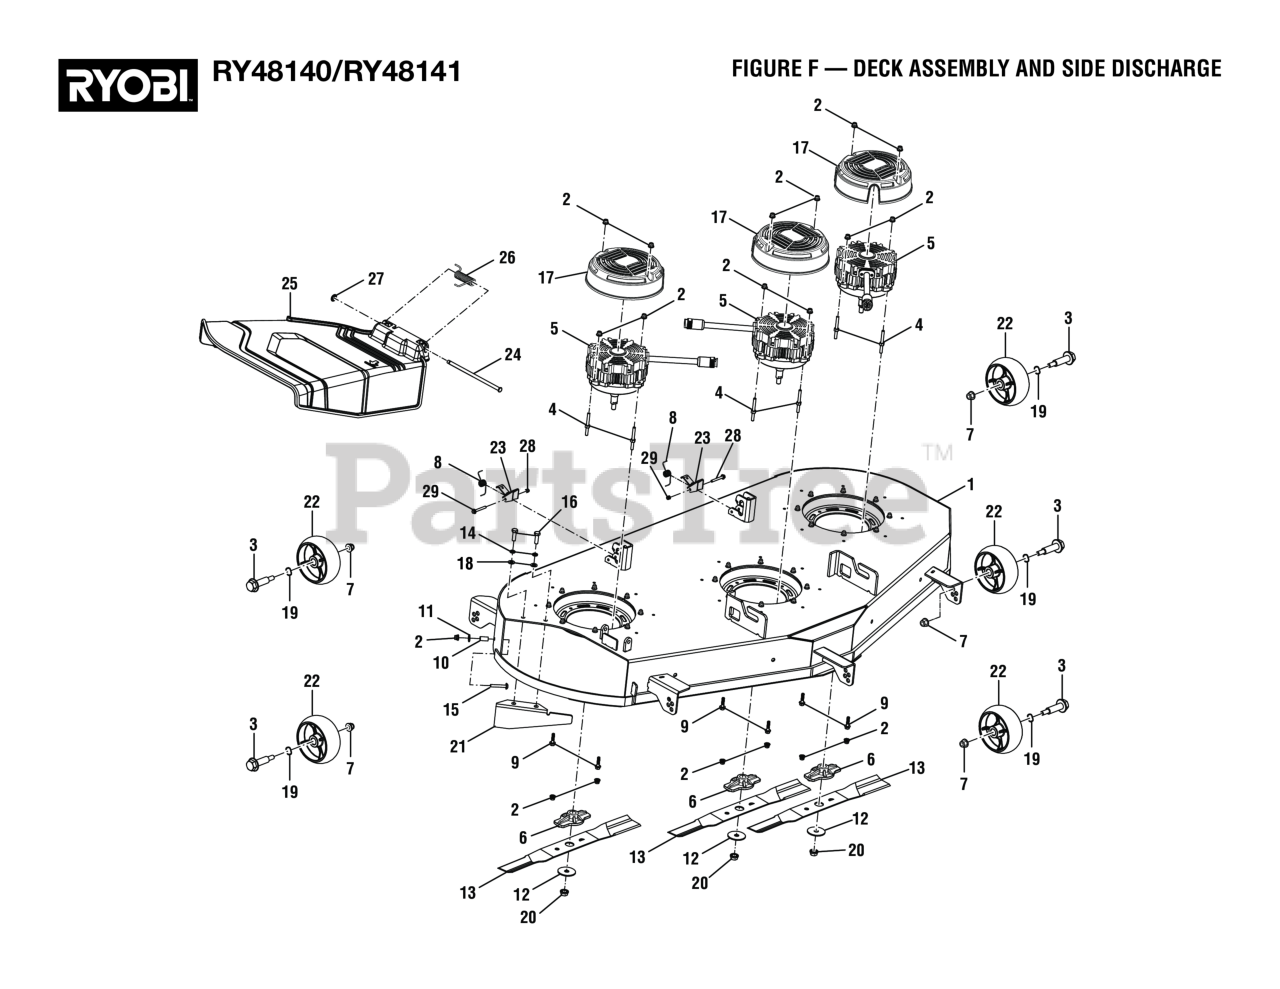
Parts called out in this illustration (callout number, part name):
1	Deck, 54 in.
2	Flange Lock Nut (M6 x 1.00)
3	Shoulder Bolt (M10 x 70 mm)
4	Threaded Stud (M6 x 35 mm)
5	Deck Motor
6	Blade Adapter
7	Lock Nut (M10 x 1.5 mm)
8	Deck Clip Spring
9	Flange Bolt (M6 x 25 mm, Hex Hd.)
10	Deck Bagger Chute Mounting Shaft
11	Washer (OD18 x ID6.4 x 1.6t)
12	Blade Retainer Washer
13	Blade (18.5 in.)
14	Flange Nut (M8) (For Drive Motor Controller V)
15	Screw (M6 x 40, Soc Hd.)
16	Bolt (M8 x 25 mm, Hex Hd.)
17	Deck Motor Cover, Top
18	Washer (OD16 x ID8.4 x 1.6t)
19	Spring Washer (OD20.5 x ID17 x 0.3t)
20	Flange Lock Nut (M10 x 1.25)
21	Deck Baffle (42 in.)
22	Front Deck Roller Wheel (124.5 Dia.)
23	Deck Clip Latch
24	Hinge Pin
25	Side Discharge Chute
26	Torsion Spring (19 x 62 x 3.02t)
27	Retainer Clip
28	Flange Nut (M5)
29	Bolt (M5 x 45 mm)
